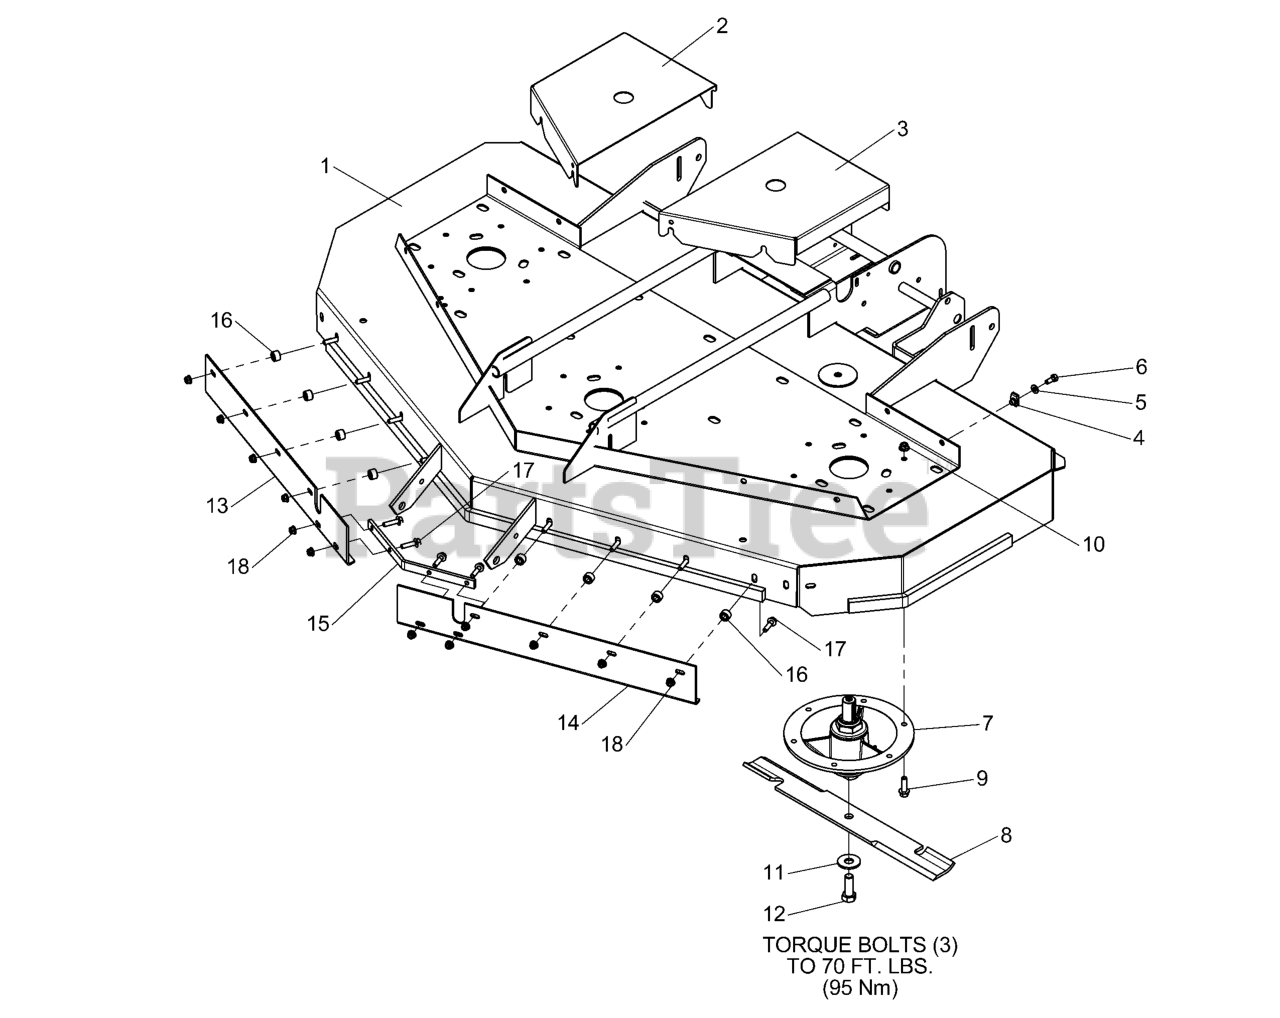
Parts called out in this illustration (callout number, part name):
1	DECK SHELL W/DECALS, 61" RD
2	DECK GUARD, RH
3	DECK GUARD, LH
4	BODY CLIP, 5/16-18-7GA MATERIAL
5	WASHER, 5/16" SAE
6	BOLT, 5/16-18 X 3/4 GD5
7	SPINDLE ASSEMBLY
8	MOWER BLADE, SAND, 21"
9	BOLT, 3/8-16 X 1-1/4" Flange Head
10	NUT, 3/8-16 Hex Nylock Flange
11	WASHER, 5/8" GRADE 8, YZ
12	BOLT, 5/8-11 X 1-3/4 GD8
13	BLOWOUT BAFFLE, RH
14	BLOWOUT BAFFLE, LH
15	BAFFLE, REINFORCEMENT - BLK
16	SPACER, .39 X .75 X .50, CZ
17	BOLT, 5/16-18 X 1-1/4" Flange Head
18	NUT, 5/16-18 Hex Nylock Flange
